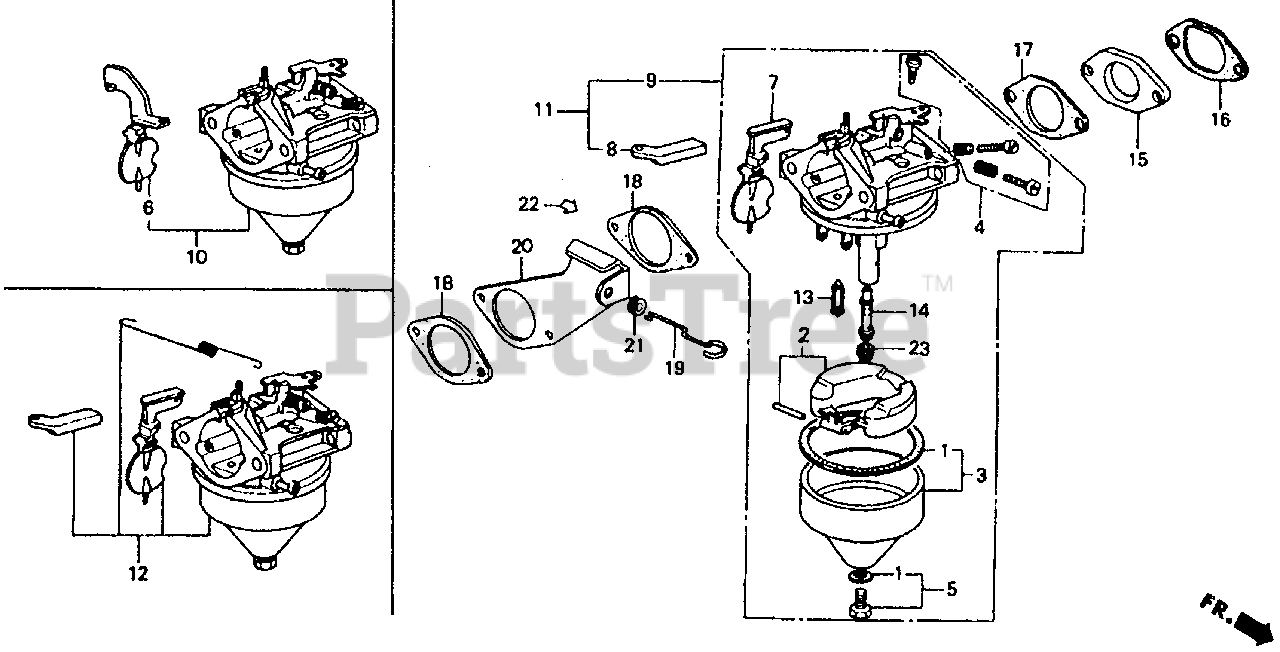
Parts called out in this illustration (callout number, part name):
1	GASKET SET
2	FLOAT SET
3	CHAMBER SET, FLOAT
4	SCREW SET A
5	SCREW SET B
6	CHOKE SET
7	CHOKE SET
8	ARM, CHOKE LEVER
9	CARBURETOR ASSY.
10	CARBURETOR ASSY.
11	CARBURETOR ASSY.
12	CARBURETOR ASSY.
13	VALVE, FLOAT
14	NOZZLE, MAIN
15	INSULATOR, CARBURETOR
16	GASKET, INSULATOR
17	GASKET, CARBURETOR
18	GASKET, AIR CLEANER
19	ROD, CHOKE CONTROL
20	STAY, CHOKE CONTROL
21	GROMMET, CHOKE ROD
22	MARK, CHOKE
23	JET, MAIN (#55)
23	JET, MAIN (#58)
23	JET, MAIN (#60)
23	JET, MAIN (#62)
